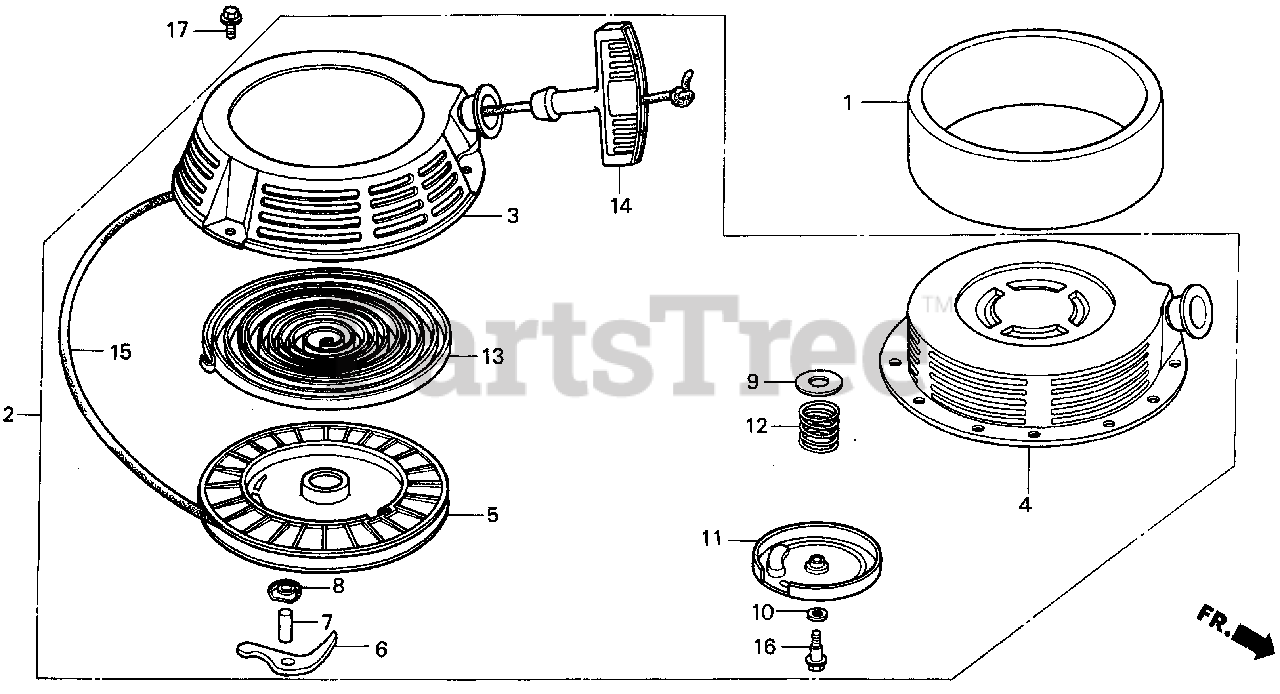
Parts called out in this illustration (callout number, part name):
1	FILTER, AIR
2	STARTER ASSY., RECOIL *R8* (BRIGHT RED)
4	CASE, RECOIL STARTER *R8* (BRIGHT RED)
5	REEL, STARTER
6	RATCHET, STARTER
7	SHAFT, RATCHET
8	PLATE, GUIDE
9	PLATE A, FRICTION
10	PLATE B, FRICTION
11	COVER, REEL STARTER
12	SPRING, FRICTION
13	SPRING, RETURN
14	GRIP, STARTER
15	ROPE, STARTER (#6X64") (N/A: USE ALT P/N 08560-ZG921-11)
16	BOLT, REEL COVER
17	BOLT, FLANGE (6X10)
17	BOLT, FLANGE (6X8)
